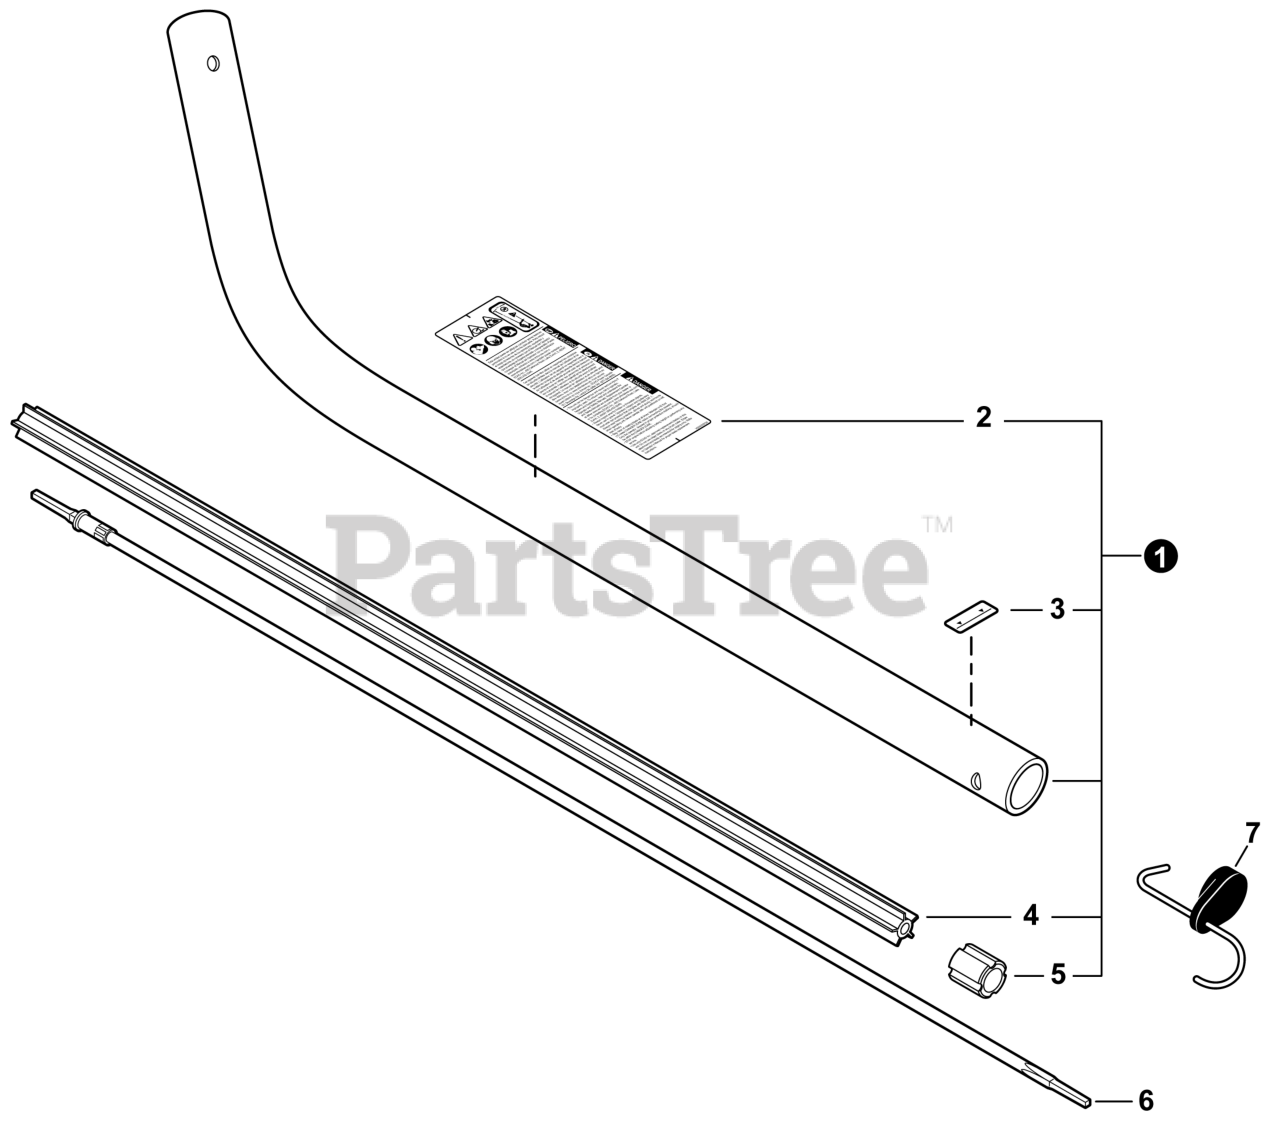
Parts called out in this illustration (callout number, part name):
1	MAIN PIPE, PAS EDGER
2	LABEL - CAUTION
3	LABEL - ALIGNMENT
4	LINER - FLEXIBLE
6	DRIVESHAFT - FLEXIBLE
7	HANGER, ATTACHMENT
